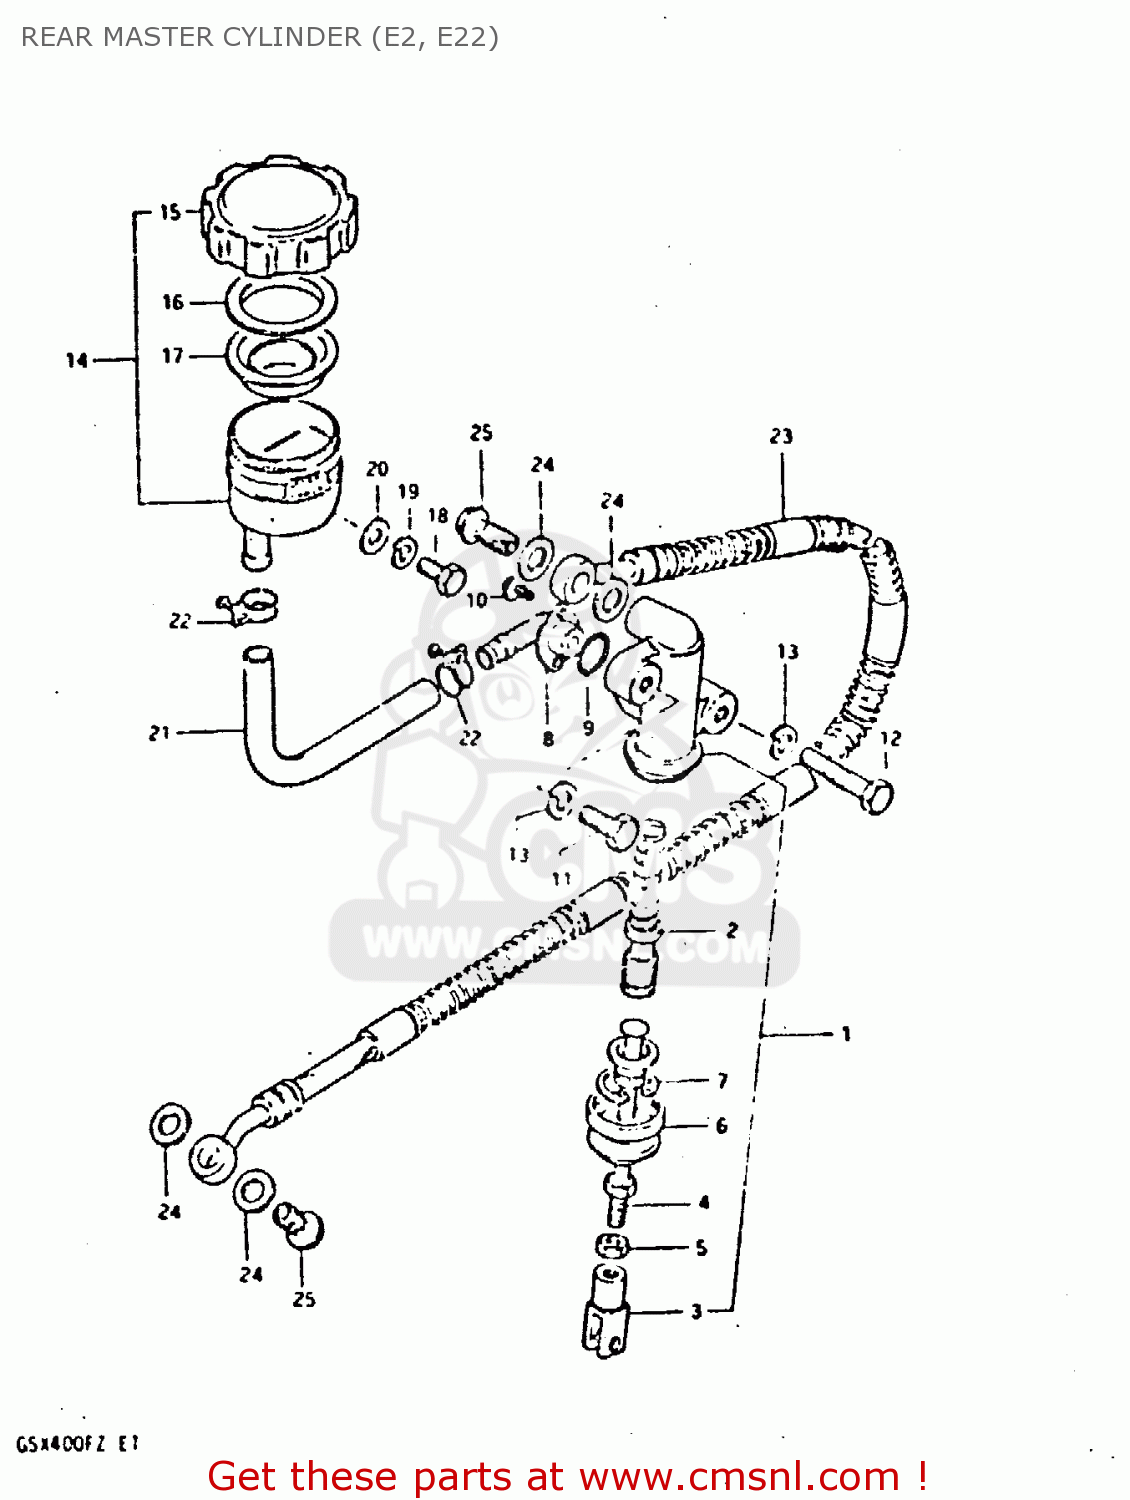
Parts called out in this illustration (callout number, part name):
1	CYLINDER ASSEMBLY,REAR MASTER
2	PISTON/CUP SET
3	YOKE
4	ROD,REAR MASTER CYLINDER
5	NUT
6	BOOT
7	CIRCLIP
8	CONNECTOR,HOSE
9	O RING
10	SCREW
11	BOLT
12	BOLT 8X55
13	LOCK WASHER
14	TANK ASSEMBLY,RESERVOIR
15	CAP
16	PLATE,DIAPHRAGM
17	DIAPHRAGM
18	BOLT, UPPER
19	LOCK WASHER
20	WASHER
21	HOSE
22	CLAMP
23	HOSE, REAR BRAKE
24	WASHER
25	BOLT,UNION
